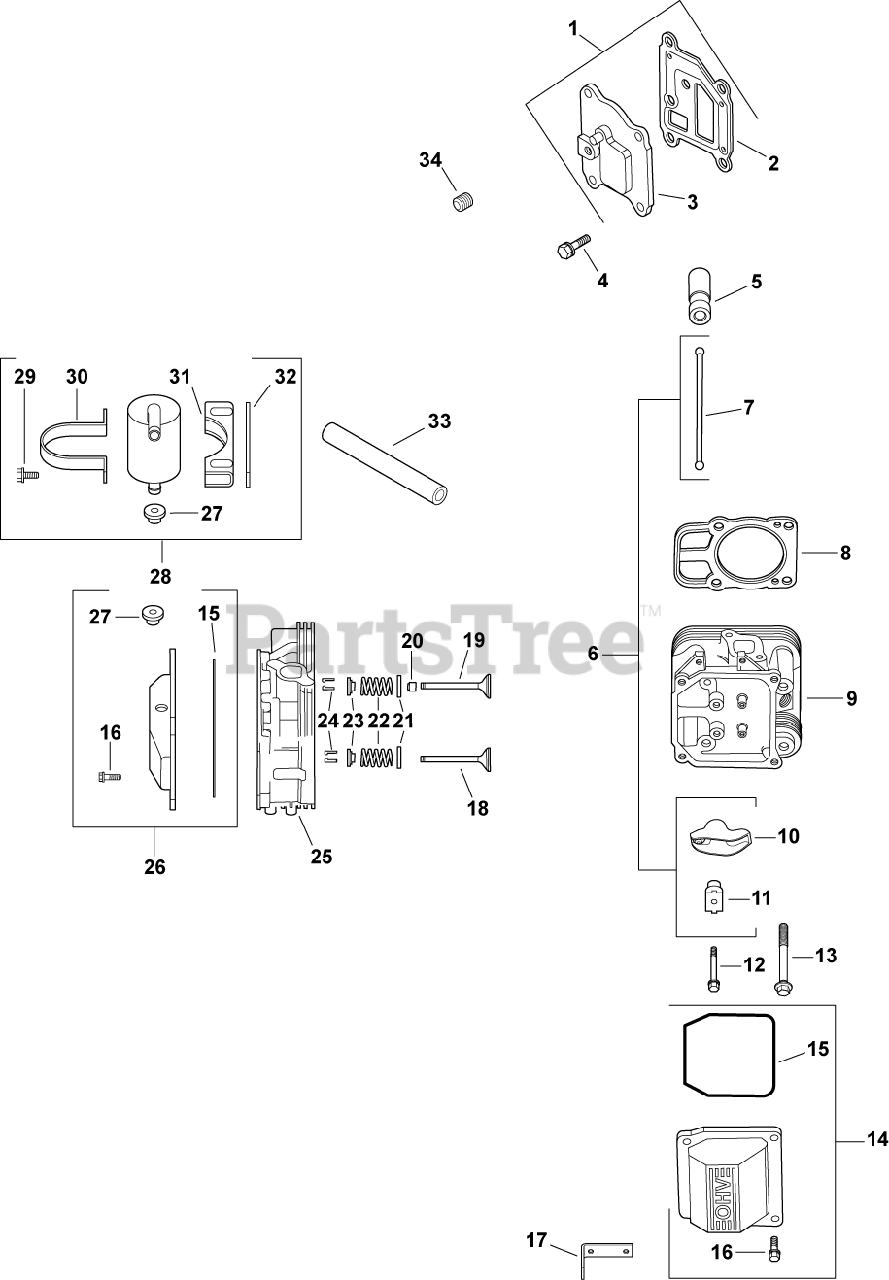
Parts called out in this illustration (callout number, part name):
1	KIT, BREATHER COVER W/GASKET
2	GASKET, BREATHER-USE 24 041 67-S
3	COVER, BREATHER -USE 24 096 125-S
4	SCREW,FLG THD FRM M6X1.0X20-(#25086396S)
5	LIFTER, HYDRAULIC VALVE-USE 25 351 10-S
6	KIT, VALVE TRAIN
7	ROD, PUSH
8	KIT, CYL HEAD GASKET (C17-22)
9	HEAD, ASSEM CYLINDER #2 -USE 24 318 113-
10	ARM, ROCKER
11	PIVOT, ROCKER ARM
12	SCREW, FLG M6X1.0X34
13	SCREW - USE 62 086 08-S
14	KIT, VALVE COVER-PLAIN
15	O-RING (YELLOW) -USE 24 153 30-S
16	SCREW, FLG M6X1.0X30
17	STRAP, LIFTING-USE 25 445 03-S
18	VALVE, EXHAUST (STD) - USE 32 016 01-S
19	VALVE, INTAKE (STD)
20	SEAL, VALVE STEM - (#2503214S)
21	RETAINER, SPRING
22	SPRING, VALVE
23	RETAINER, VALVE SPRING - USE 25 173 28-S
24	KIT, RETAINER
25	HEAD, ASSEM CYLINDER #1 -USE 24 318 105-
26	KIT, VALVE COVER
27	GROMMET, RUBBER
28	KIT, BREATHR SEPARATR-(#24755241S)
29	SCREW,FLG THD FRM M5X0.8X16-(#25086398S)
30	STRAP, BREATHER - USE 24 755 241-S
31	BRACKET, BREATHER SEPARATOR
32	SPACER
33	HOSE, BREATHER-USE 24 326 63-S
34	PLUG, CTSK PIPE 1/8"
2401602-S	VALVE, EXHAUST (.25)
2401702-S	VALVE, INTAKE (.25)
